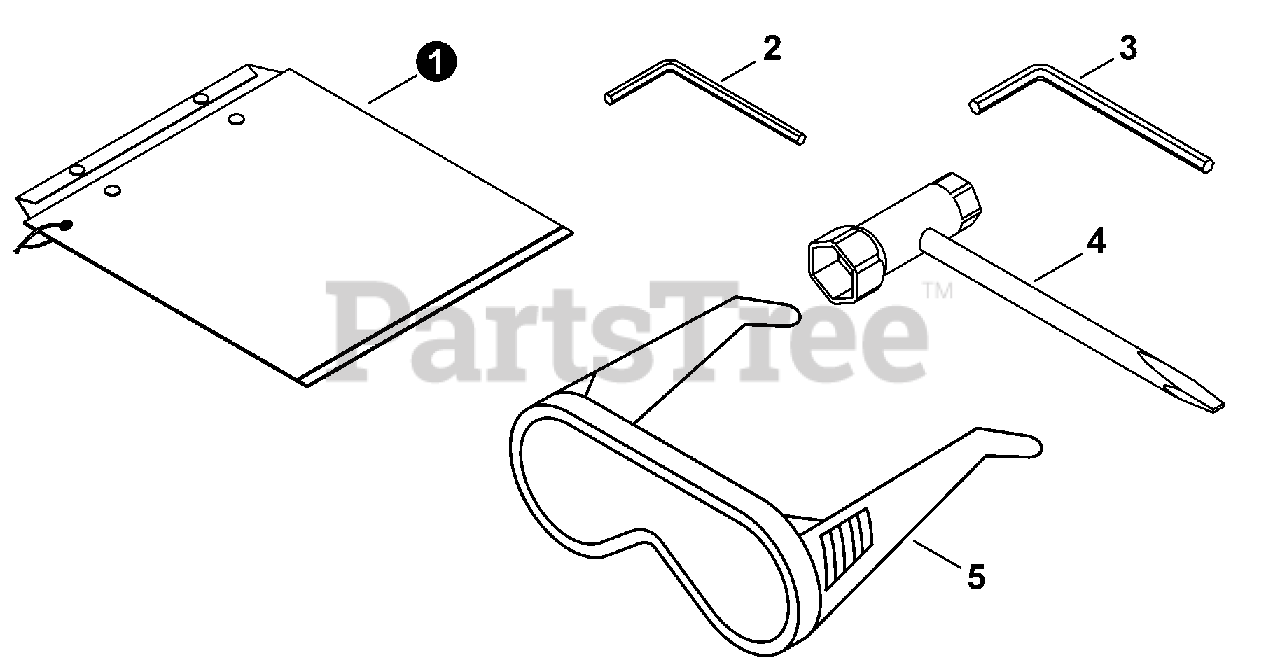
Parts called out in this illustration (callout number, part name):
1	BAG, TOOL
2	WRENCH, ALLEN 4 MM
3	WRENCH, ALLEN 5 MM
4	T-WRENCH 17×19 MM
5	GLASSES, SAFETY
